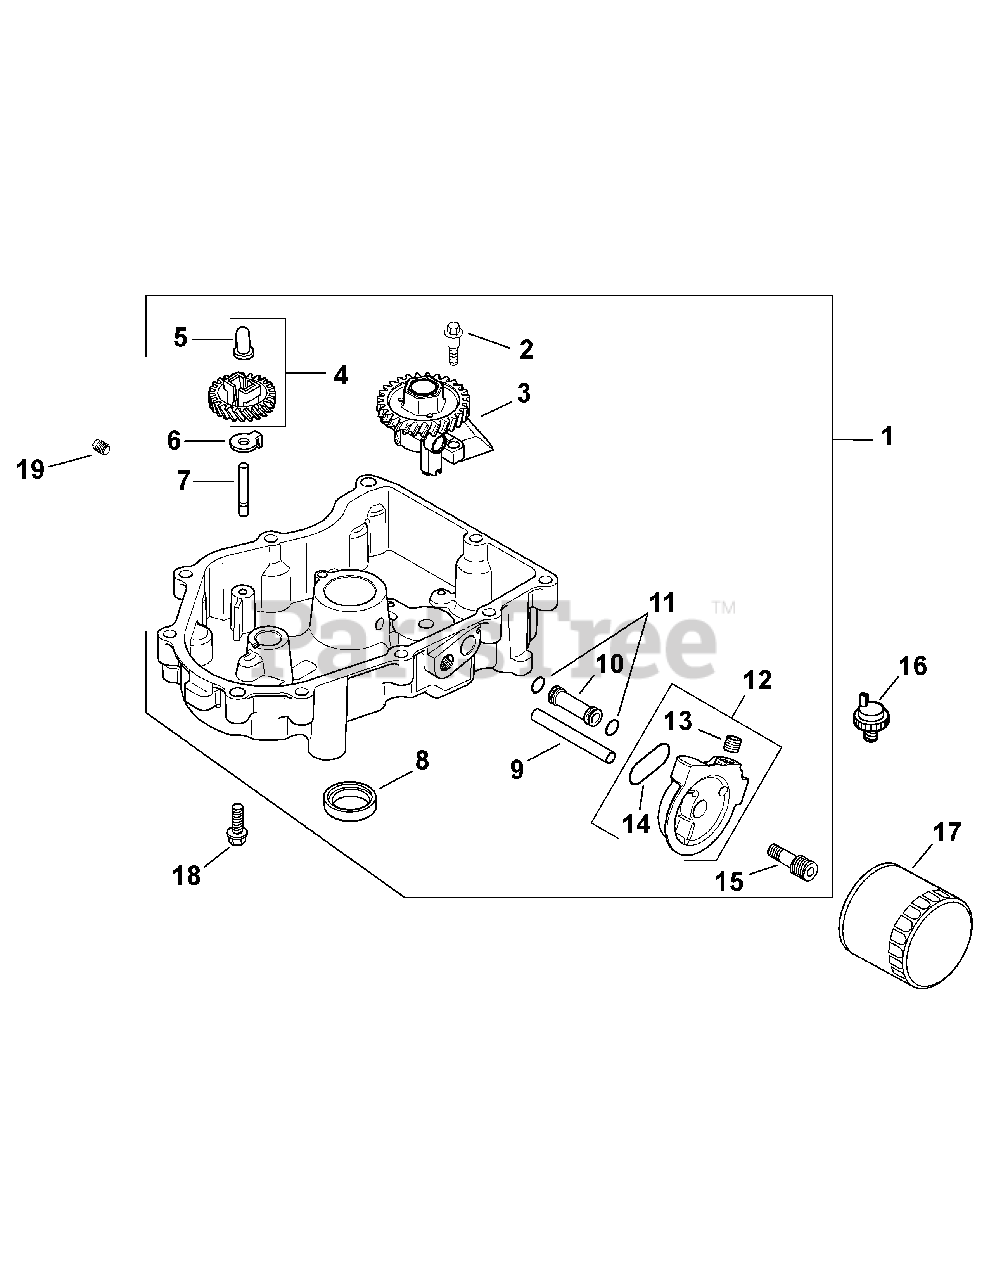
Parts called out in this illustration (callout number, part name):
1	Pan Assembly, Oil (Incl. Ref. 2-15)
2	Screw, Flnge Thrd. Frmng M6 x 1.0 x 26.5
3	Pump Assembly, Oil
4	Kit, Governor Gear w/Pin (Incl. Ref. 5)
5	Pin, Governor Regulating
7	Shaft, Governor Gear
8	Seal, Oil (PTO End)
9	Tube, Oil Feed - Filter to Pan
10	Tube, Oil Feed - Pan to Filter
11	O-Ring, Oil Pick-up
12	Kit, Oil Filter Adapter
13	Plug, Pipe, 1/8
14	O-Ring, Oil Filter Adapter
15	Nipple, Oil Filter
16	Switch, Oil Pressure
18	Screw, Flange, M8 x 1.25 x 45
19	Plug, Sq. Hd. Pipe, 3/8
